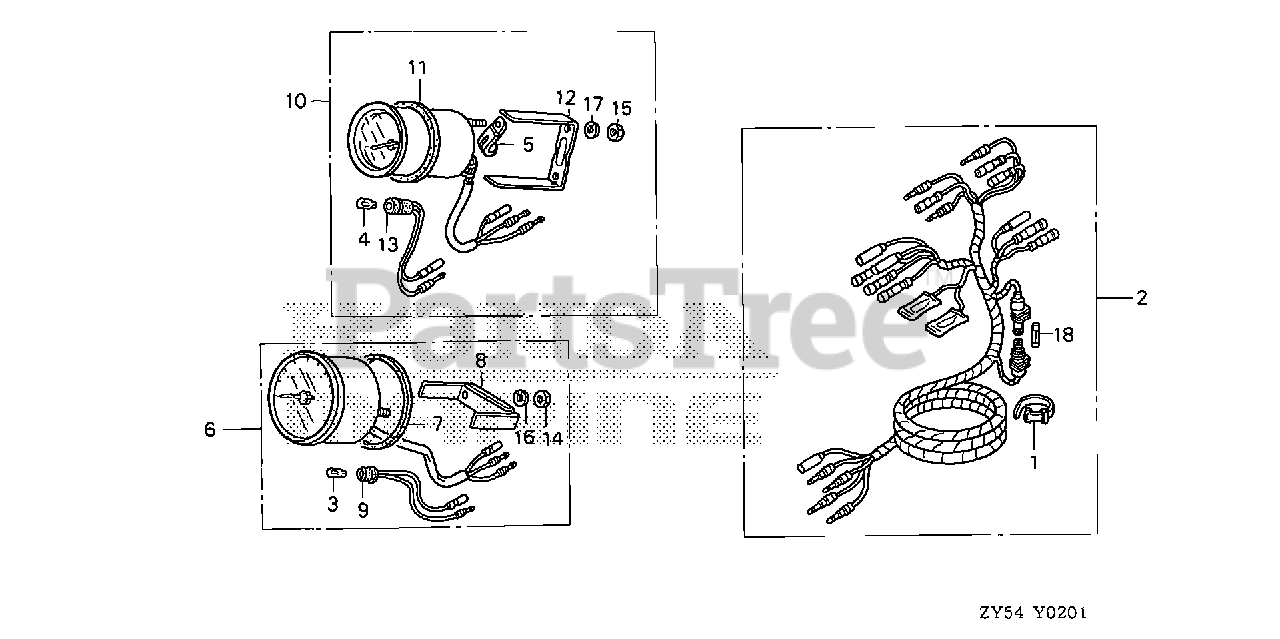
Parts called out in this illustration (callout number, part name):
1	BAND B1, CABLE Use up to Frame SN 1001879.
2	HARNESS ASSY., METER (A)
3	BULB, WEDGE BASE (T10) (12V 1.7W) (STANLEY)
4	BULB, WEDGE BASE (12V1.7W) (TOSHIBA)
5	CLAMP
6	TACHOMETER ASSY.
7	GASKET
8	BRACKET (TO 1015209) (FROM 1015210)
9	SOCKET (TO 1015209) (FROM 1015210)
10	METER ASSY., TRIM
11	GASKET (TO 1015209) (FROM 1015210)
12	BRACKET (TO 1015209) (FROM 1015210)
13	SOCKET (TO 1015209) (FROM 1015210)
14	NUT, HEX. (5MM)
15	NUT, HEX. (4MM)
16	WASHER, SPRING (5MM)
17	WASHER, SPRING (4MM)
18	FUSE A (10A)
